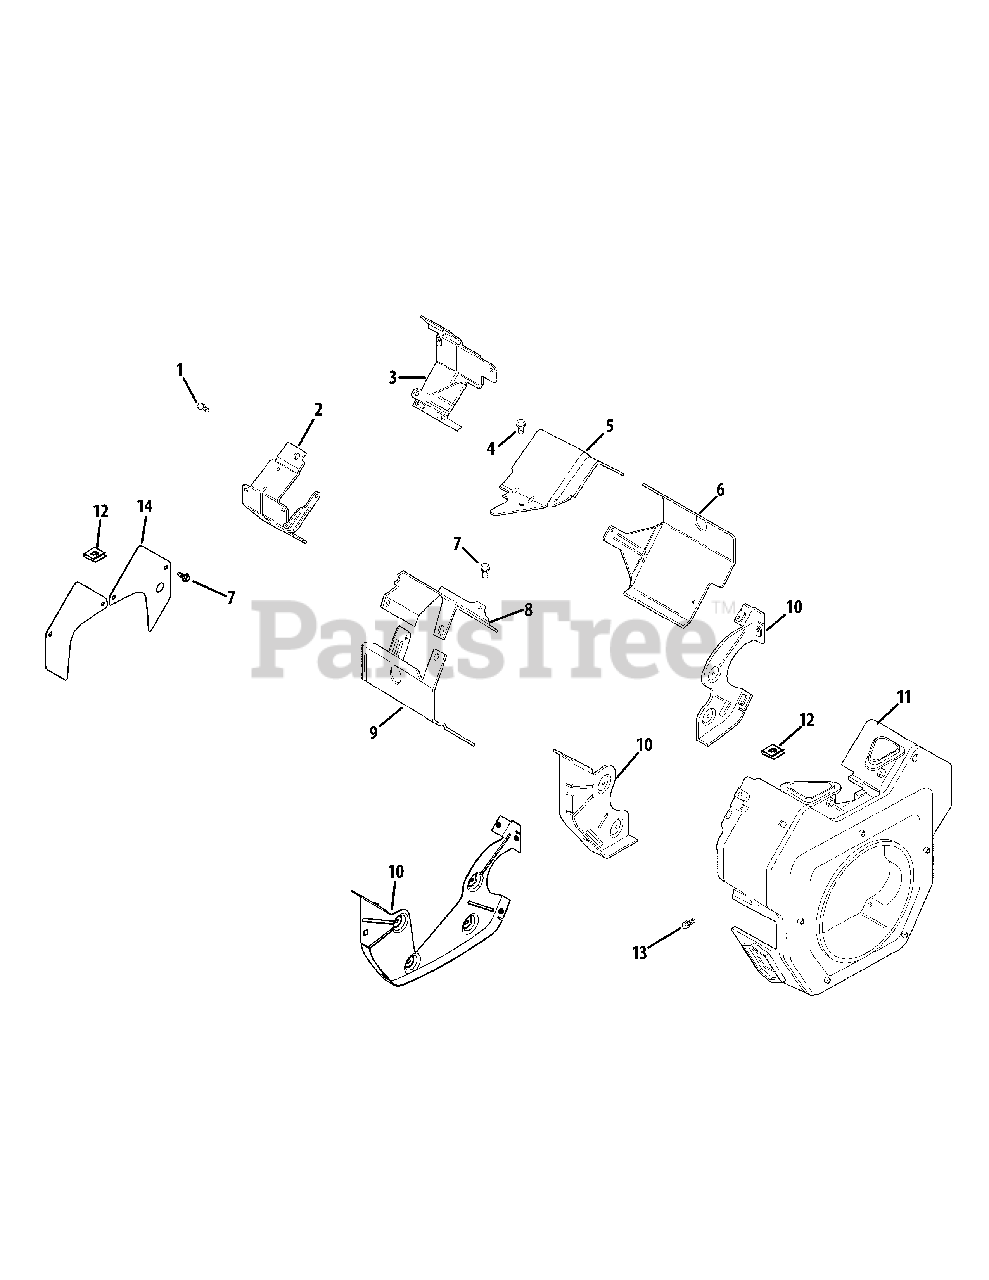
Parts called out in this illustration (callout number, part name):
1	Flange Screw, M6 x 1.0 x 10
2	Ducted Air-Oil Filter Baffle
3	Ducted Air-Starter Baffle
4	Thread Forming Screw
5	Valley Baffle, #1 Cylinder
6	Cylinder Baffle Kit, #1 Side
7	Thread Forming Screw
8	Valley Baffle, #2 Cylinder
9	Cylinder Baffle Kit, #2 Side
10	Backing Plate Kit
11	Blower Housing Assembly Kit
12	Baffle Mounting Clip
13	Thread Forming Screw
14	Access Panel Kit
